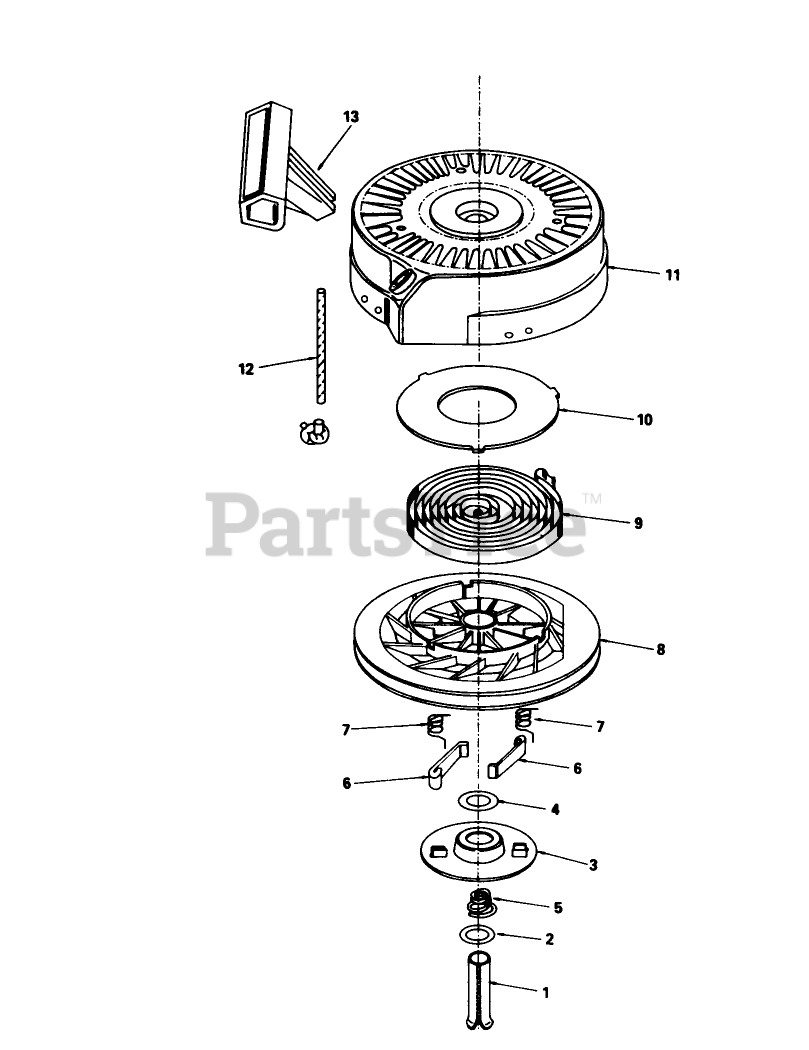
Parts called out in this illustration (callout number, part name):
1	Pin Spring
3	Retainer
5	Brake Spring
6	Dog-Starter
7	Spring-Dog
8	Pulley
9	Rewind Spring
10	Cover-Spring
11	Housing-Starter
12	Rope-Starter (98 cut to length)
13	Handle-Starter
